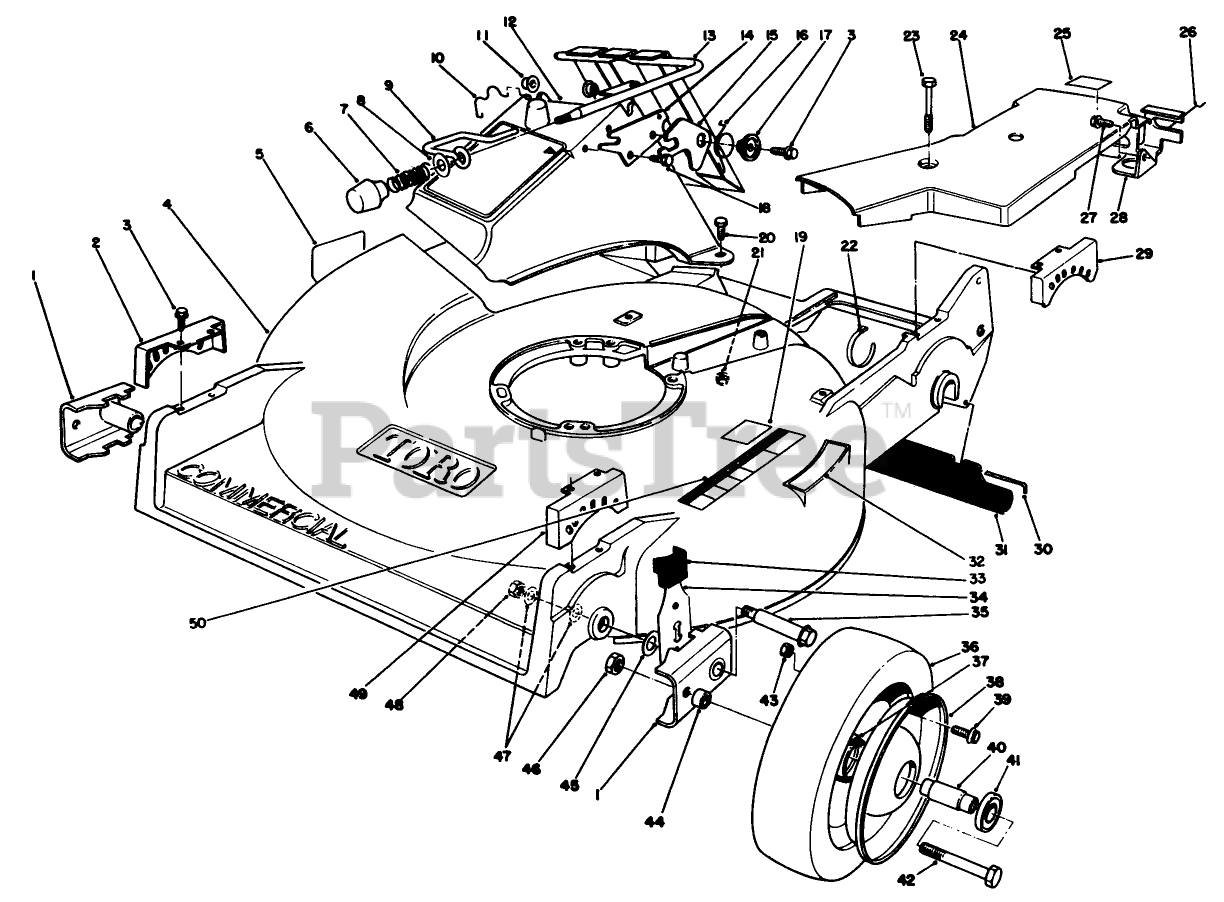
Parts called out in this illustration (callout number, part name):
1	ARM-PIVOT, FRONT
2	QUADRANT-FRONT, RH
3	SCREW-HWHTF
5	DECAL-DANGER
7	COMPRESSION SPRING
8	WASHER-FLAT
9	DOOR LATCH
10	DOOR RETAINER
11	BUSHING-NYLON
12	DISCHARGE CHUTE *B
14	DOOR LATCH PLATE
15	SAFETY LATCH
16	TORSION SPRING
17	DOOR SPACER
18	SCREW-HWH
19	DECAL-STANDARD, SAFETY
20	SCREW-HH
21	NUT-LOCK, NI
22	TIE-CABLE
23	SCREW-HWH
26	RETAINER-CABLE
27	SCREW-HWHTF
29	QUADRANT-REAR, LH
30	ROD-SHIELD
32	STEP PAD DECAL
33	KNOB-ARM
34	FRONT SPRING ARM ASM
35	WHEEL BOLT
37	HUB-BEARING
39	SCREW-HHF
40	SPACER-BEARING
41	BEARING-WHEEL
42	SCREW-HH
43	NUT-LOCK, NI
44	SPACER-WHEEL
45	WASHER-THRUST
46	NUT-LOCK, CONE
47	WASHER
49	QUADRANT-FRONT, LH
50	DECAL-INSTRUCTION, SAFETY
